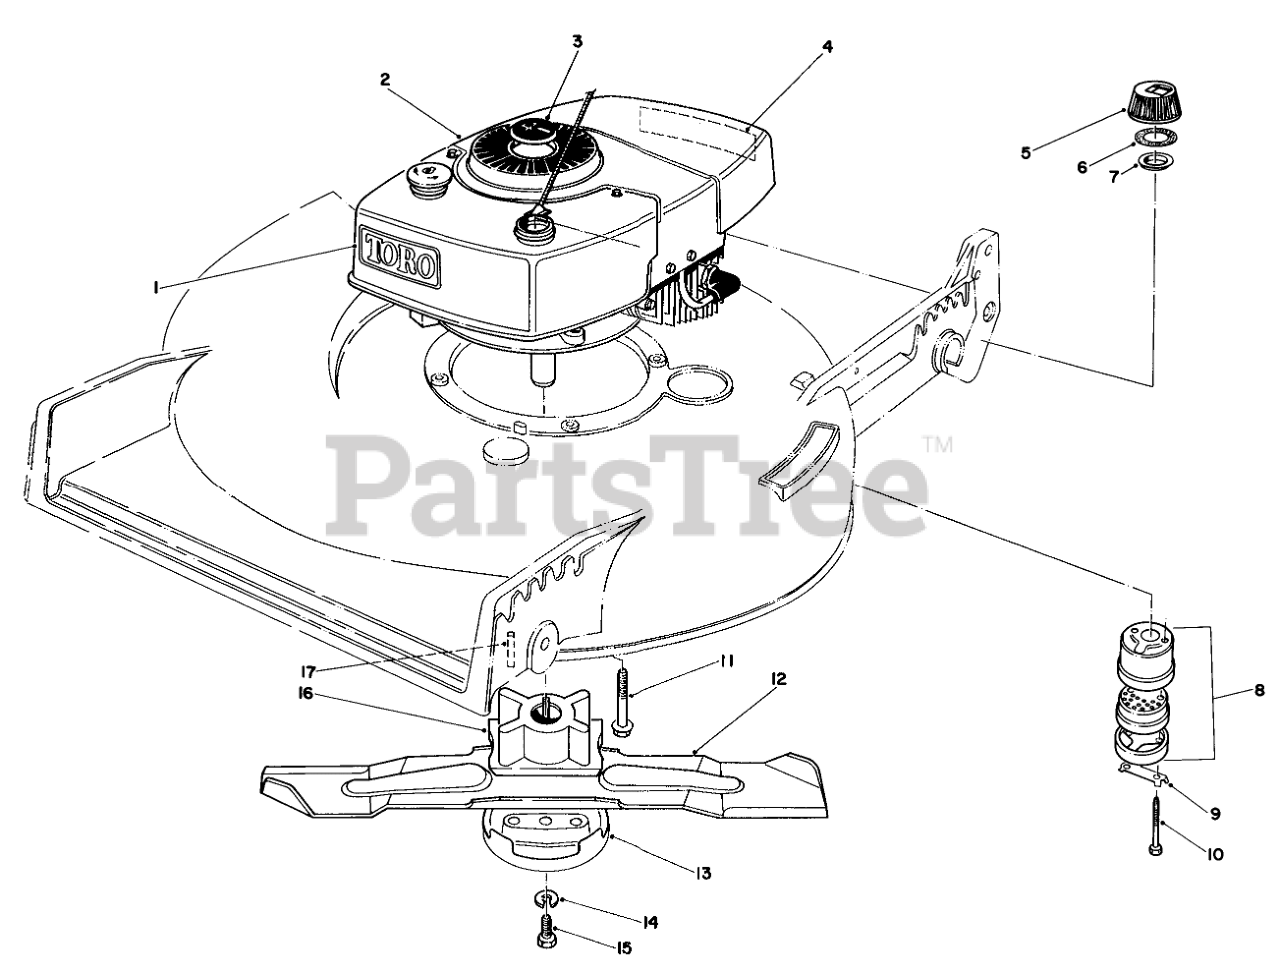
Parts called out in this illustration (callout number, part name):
1	Decal Tow
2	Engine
3	PLUG BUTTON
4	Decal-Maintenance
5	Fuel Cap Assembly (Incl. Ref. #6 & 7)
6	GASKET
7	GAS CAP BAFFLE
8	Muffler Assembly (Incl. Ref. #9 & 10)
9	CLIP - LOCKING
10	SCREW-HH
11	3/8-16 X 2 CAPSCREW
12	BLADE-21in
13	Anti Scalp Cup
14	WASHER-LOCK
15	SCREW-BLADE
16	BLADE RETAINER(DEEP)
17	KEY-SQUARE
